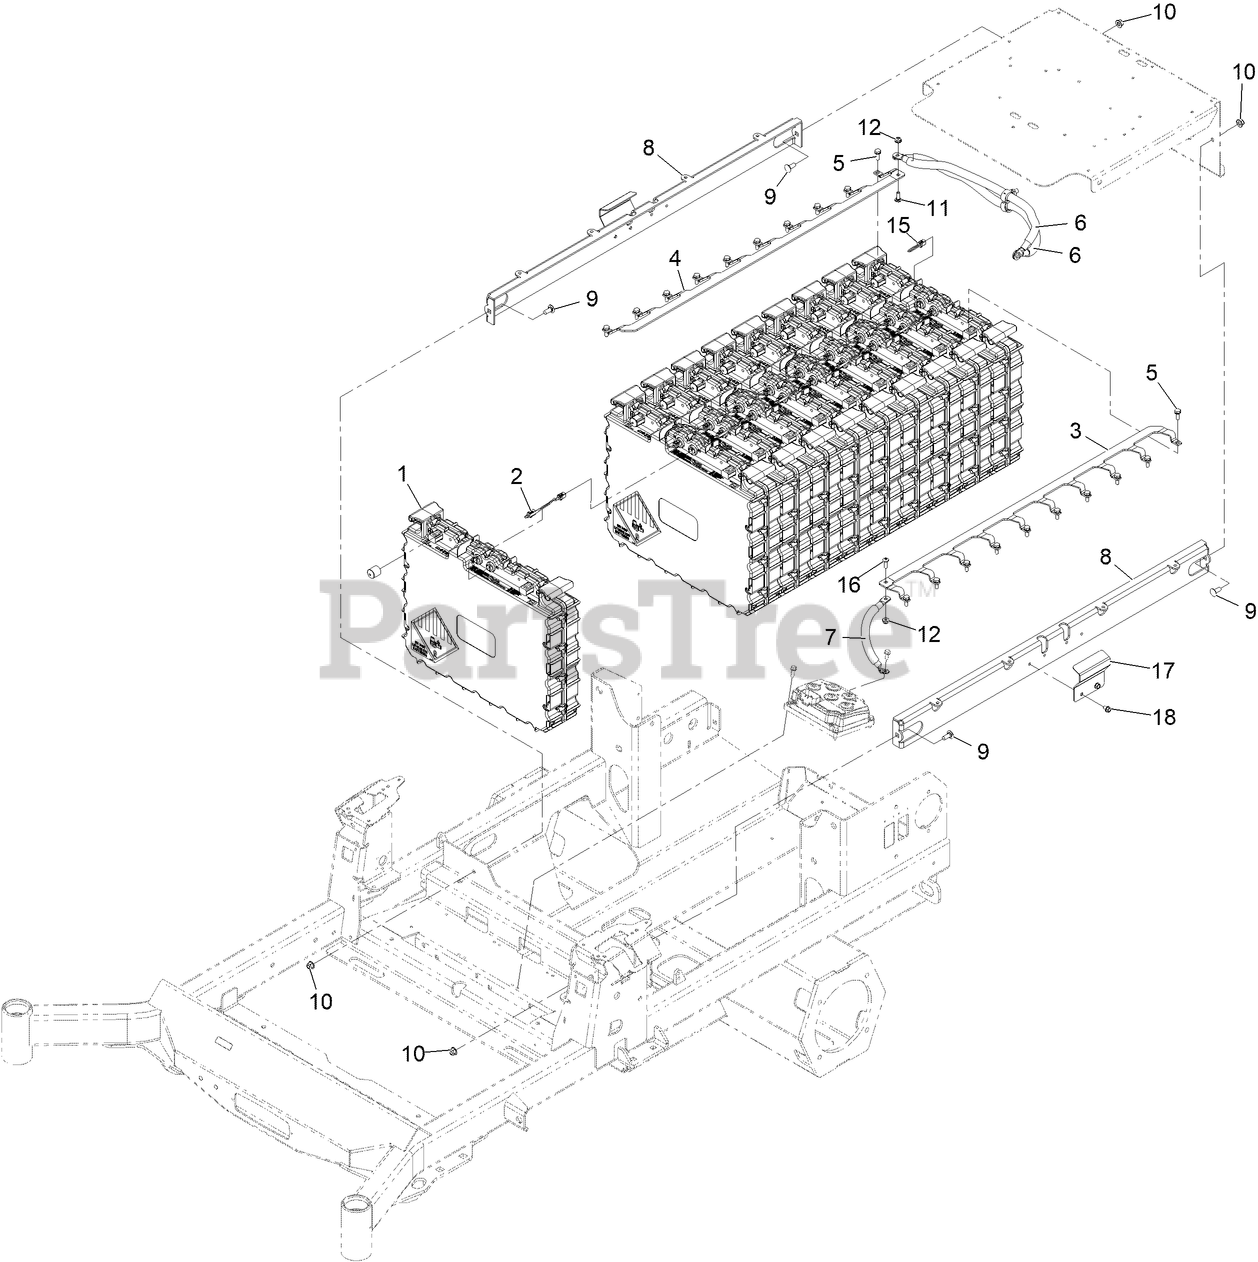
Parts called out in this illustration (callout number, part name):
1	BATTERY ASM
2	HARNESS-WIRE, DATA INTERFACE
3	BUSBAR-10, BK
4	BUSBAR-10, RD
5	SCREW-SEMS
6	CABLE-BATTERY, RD ASM
7	CABLE-BATTERY, BK ASM
8	PLATE-RETAINER
9	SCREW-CARR
10	NUT-HF, NI
11	BOLT-CARR
15	HARNESS-WIRE, CAN TERMINATOR
16	SCREW-PH
17	PLATE-COVER
18	SCREW-HWH
